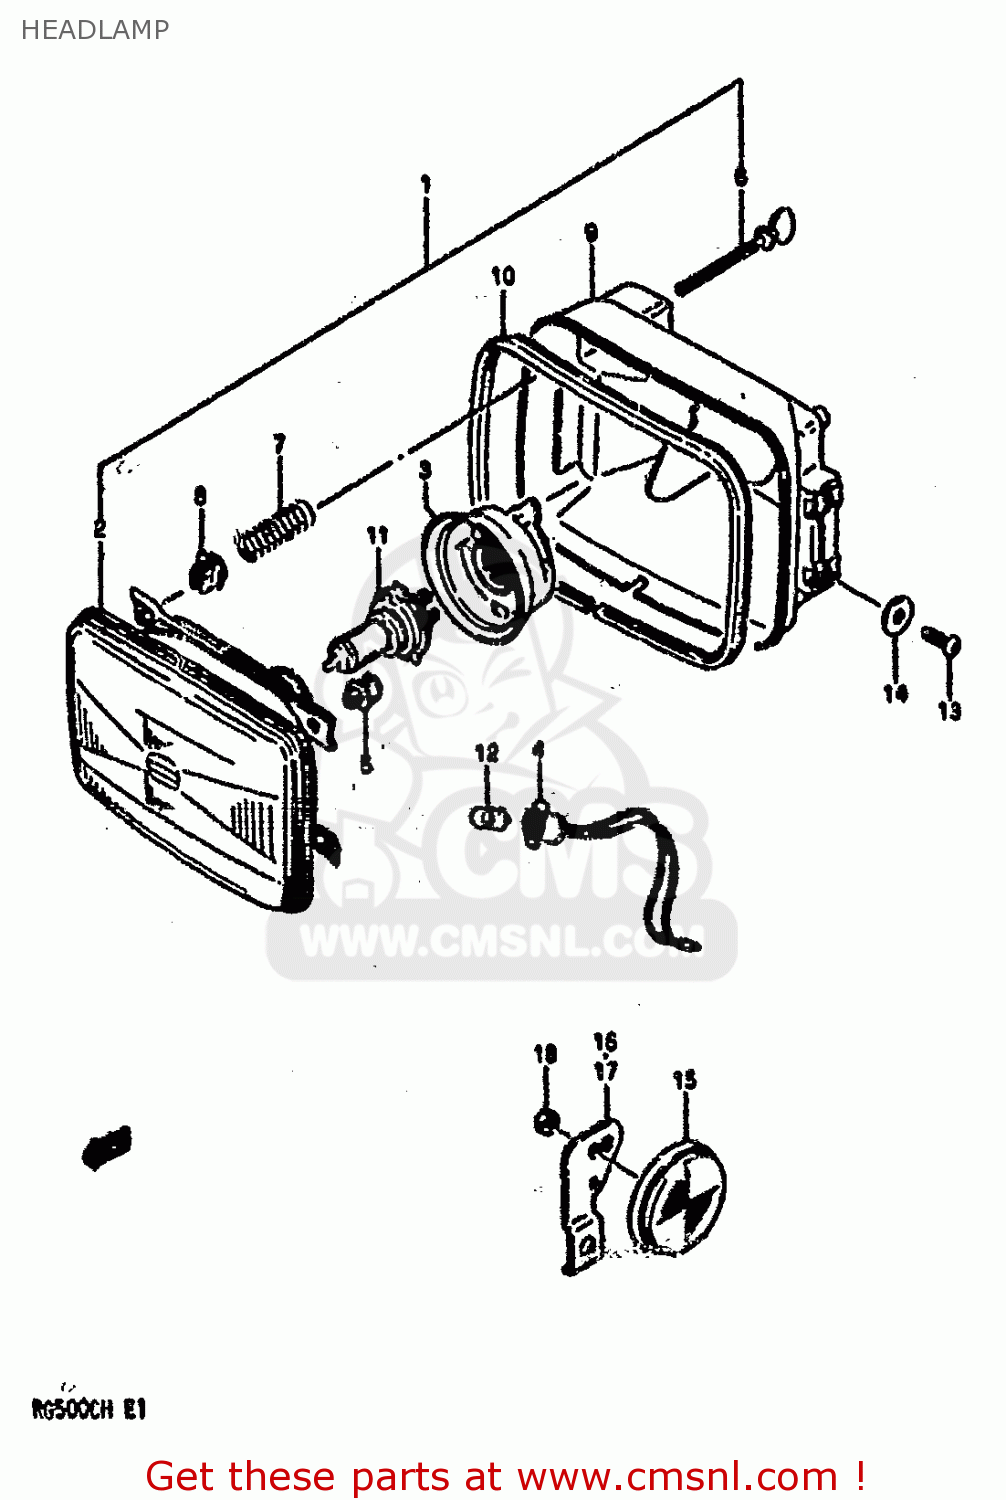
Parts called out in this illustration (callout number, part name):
1	HEADLAMP ASSY
2	UNIT
3	COVER,SOCKET
4	SOCKET
5	SCREW,SPHERICAL
6	SCREW,ADJUSTER
7	SPRING
8	NUT
9	HOUSING
10	GASKET (NAS)
11	BULB(12V60/55W,H4)
12	BULB(12V4W)
13	SCREW
14	WASHER(6,5X22X1.6)
15	REFLECTOR,REFLEX FR
16	BRACKET, RH
17	BRACKET, LH
18	LOCK WASHER
